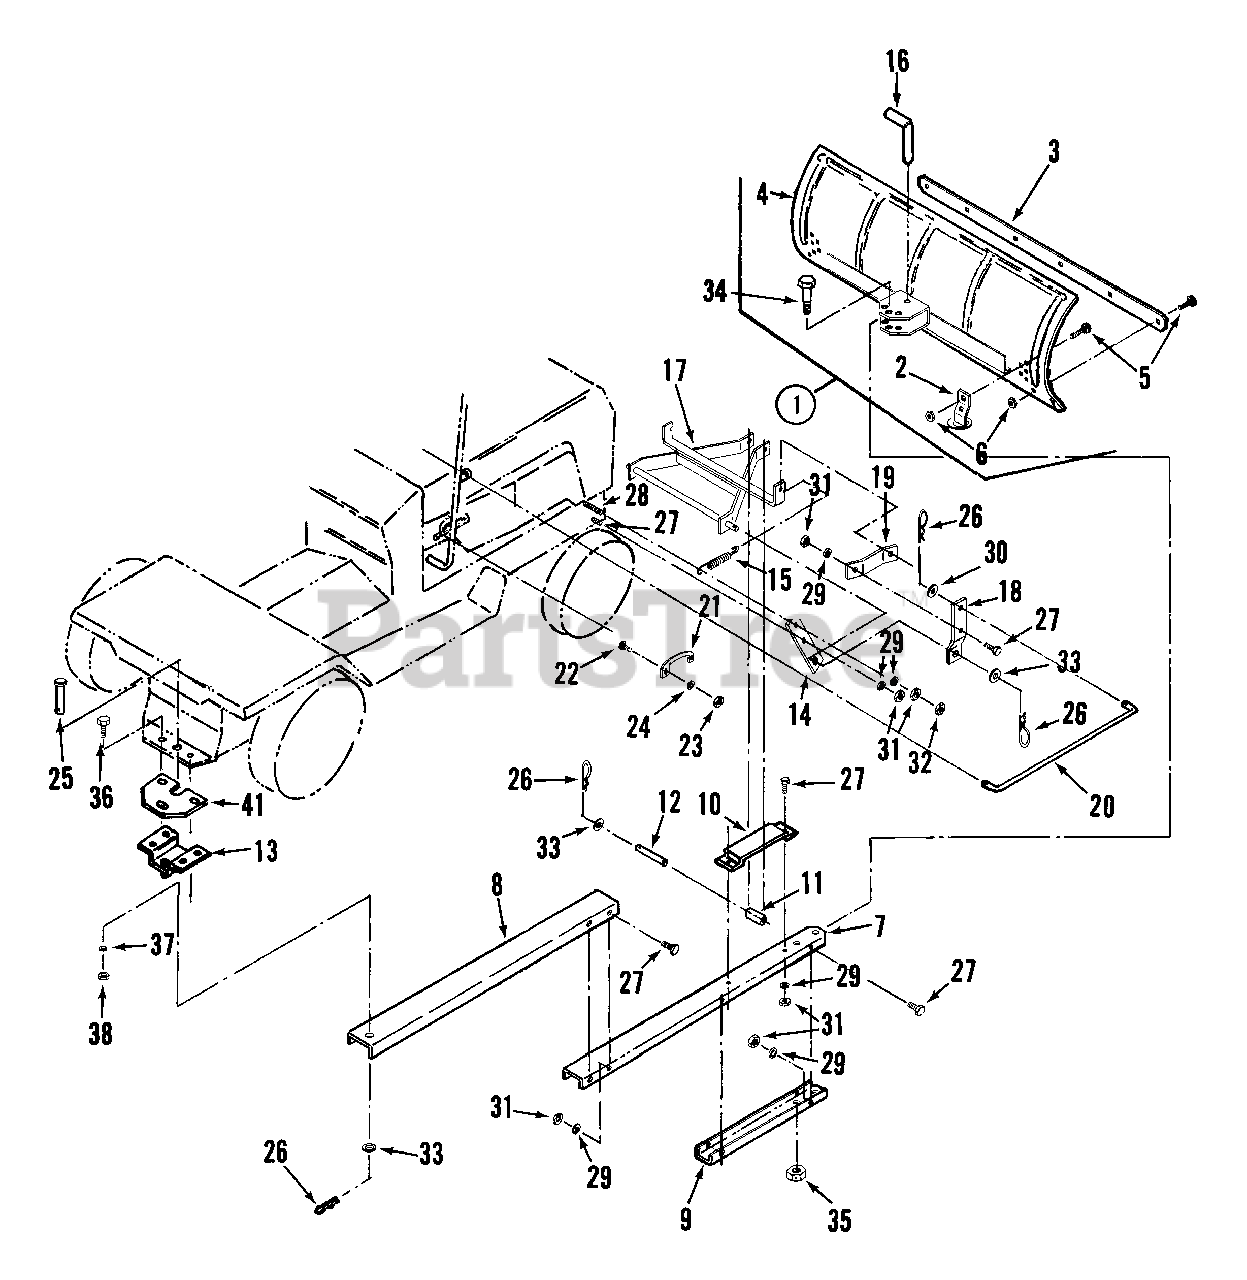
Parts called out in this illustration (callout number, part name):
1	ASSEMBLY, 42" Blade
2	STRUCTURE, Slide
3	SCRAPER
5	BOLT, 3/8-16 x 3/4" Square Neck Carriage, Gr. 2
6	NUT, 3/8-16 Hex Center Lock, Grade B or 5
7	BEAM, Front
8	BEAM, Rear
9	PLATE, Front Hitch
10	BRACKET, Lift
11	ROLLER, Lift
12	PIN, Lift Roller
13	HITCH WELDMENT, Rear Yoke
14	PLATE, Side Support
15	SPRING, Lift Assist
16	PIN, Latch
17	STRUCTURE, Lift Yoke
18	ARM, Lift
20	ROD, Operating
21	PLATE, Quadrant Lockout
22	BOLT, 1/4-20 x 5/8" Flat Head Carriage
23	NUT, 1/4-20 Hex
24	WASHER, 1/4 Internal Tooth Lock
25	PIN, 1/2 x 2" Clevis
26	PIN, Hair Cotter
27	SCREW, 3/8-3/8-16 x 1" Hex Head Cap, Grade 5
28	SCREW, 3/8-16 x 1-1/2" Hex head Cap, Grade 5
29	WASHER, 3/8 Split Lock
30	WASHER, 3/8" Flat
31	NUT, 3/8-16 Hex, Grade 5
32	NUT, 3/8-16 Hex Center Lock, Grade B or 5
33	WASHER, 1/2 Flat
34	SCREW, 1/2-20 x 2-3/4" Hex Head Cap
35	NUT, 1/2-20 Nyloc
36	SCREW, 5/16-18 x 3/4" Hex Head Cap, Grade 2
37	WASHER, 5/16 Split Lock
38	NUT, 5/16-18 Hex
41	DRAWBAR, Short, Auxilliary
